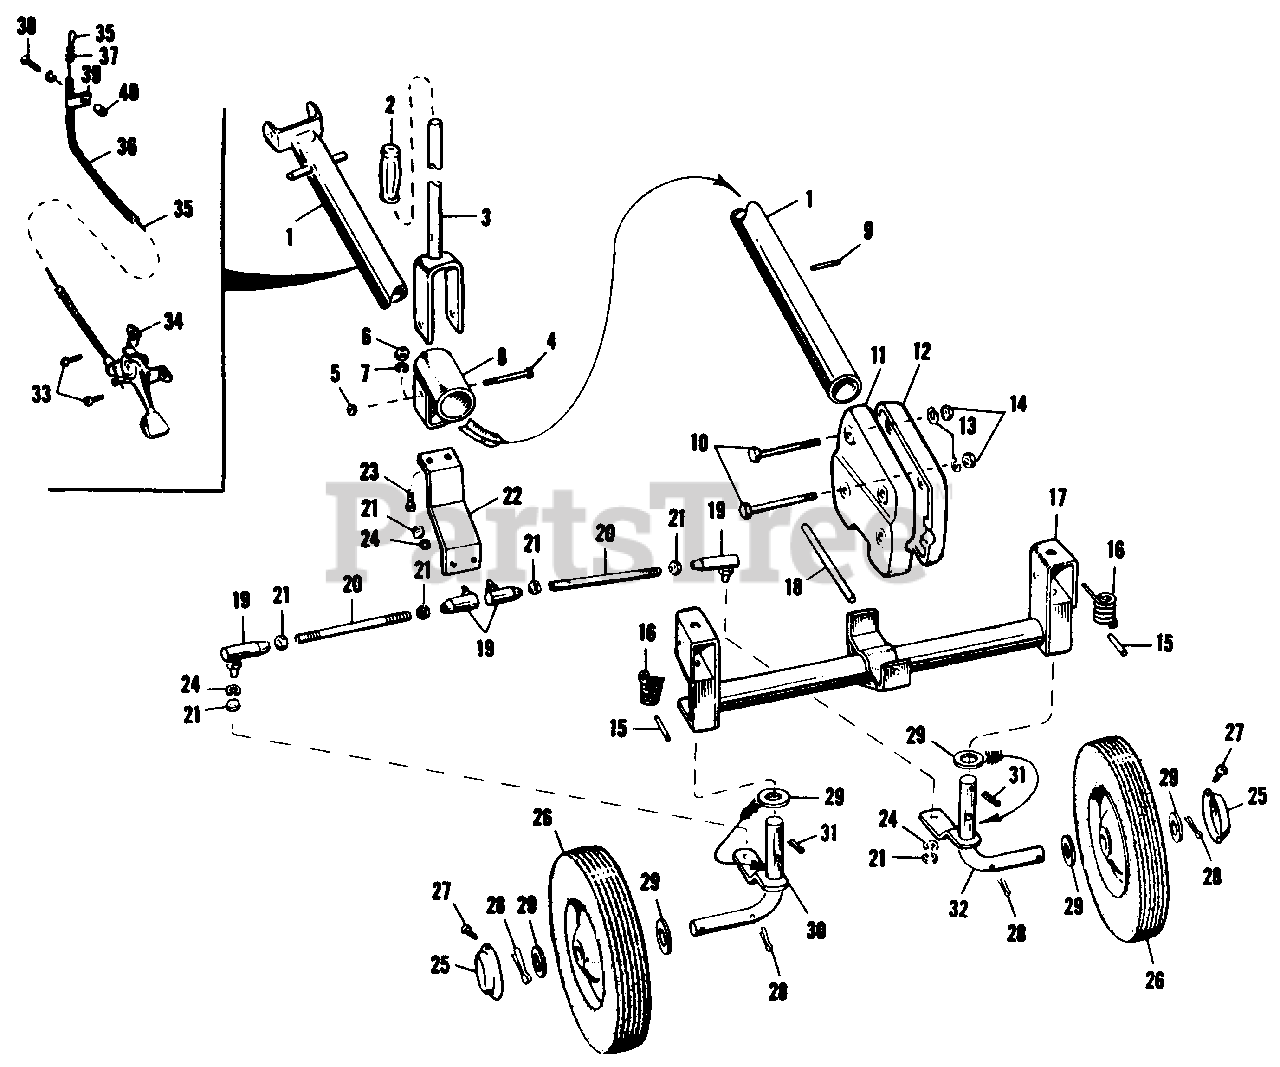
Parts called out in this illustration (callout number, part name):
1	Frame Assembly, Front
2	Grip Handle
3	Handle Assembly
8	Pivot Assembly Steering
9	Pln Roll 7/32" x 1 Long
11	Support, Front, R.H.
12	Support, Front, L.H.
16	Spring Torsion
17	Axle Assembly Front
18	Pin Pivot
19	Joint Ball
22	Arm, Lever
25	Hub Cap, Front
26	Wheel, Front, w/Tire
30	Spindle Assembly, R.H.
32	Spindle Assembly, L.H.
34	Throttle Lever Control
35	Throttle Wire
36	Throttle Cable
37	Spring, Throttle Wire
39	Clamp Cable
